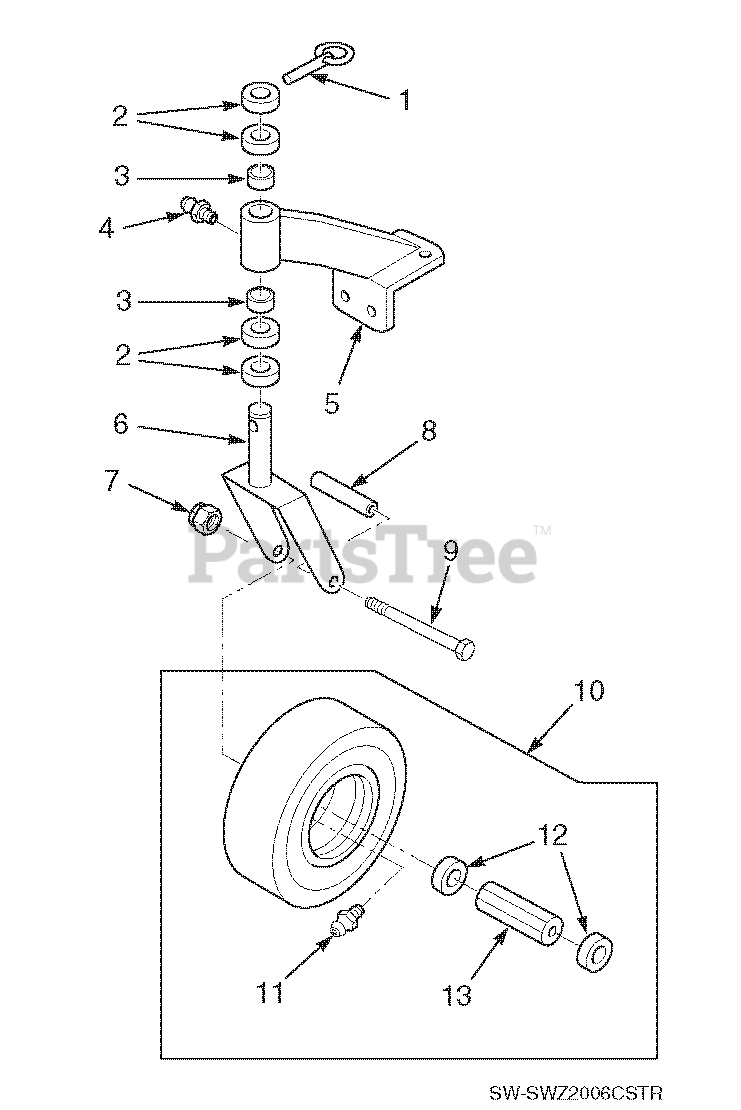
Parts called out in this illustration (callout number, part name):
1	Quick Pin
2	Spacer, Spacer Yoke, 1/2" Long
3	Bronze Bearing
4	Greasing Fitting
5	Support Assembly
6	Caster Yoke
7	Nut, Elastic Stop 1/2-13
8	Sleeve, Caster Wheel Bearing
9	Bolt, Hex Head 1/2-13 x 5-1/2"
10	Flat-Free Tire Assy.
11	Grease Fitting, 45 Degree 1/4-28
12	Retainer, Caster Wheel Bearing
13	Roller Bearing, Caster Wheel
